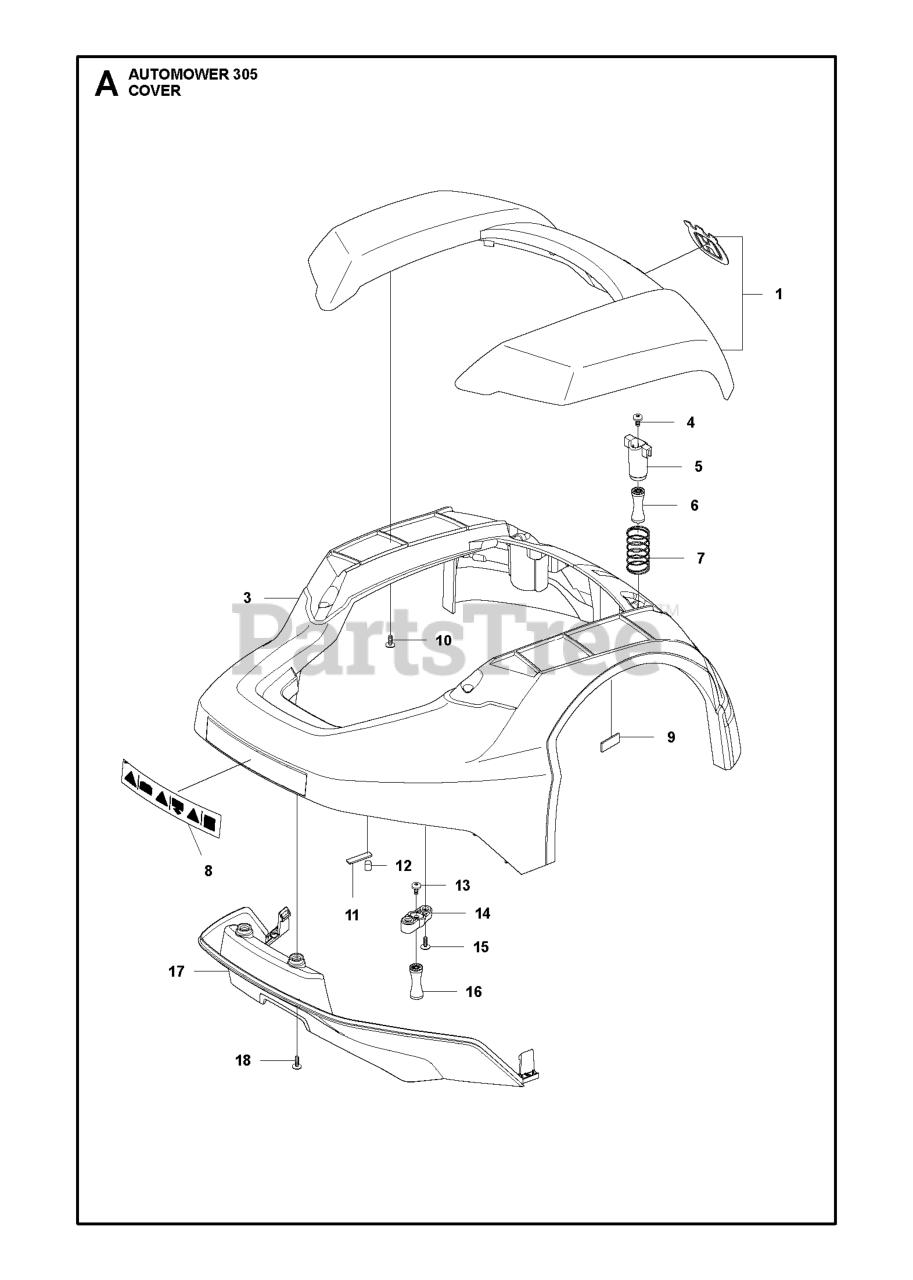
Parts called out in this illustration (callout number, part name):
9	MAGNET LIFT SENSOR
10	SCREW 14MM
11	PLATE CARRIER MAGNET
12	MAGNET COLLISION SENSOR
15	SCREW 14MM
18	SCREW SILVER 10MM
